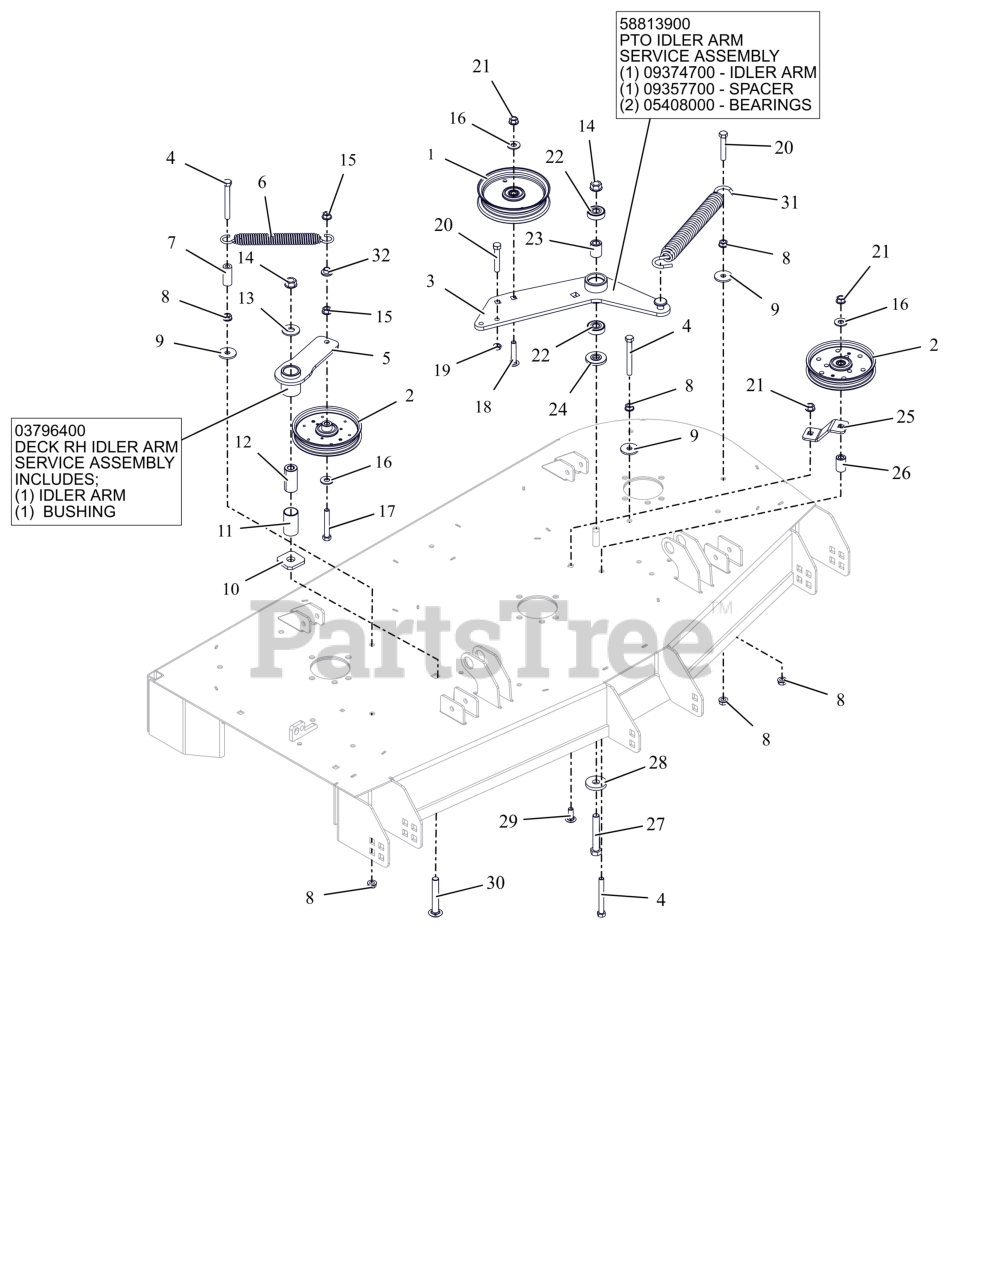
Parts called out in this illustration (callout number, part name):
1	IDLER- FLAT - 5.00" X .75"
2	IDLER- 5" FLANGED
3	WLDMT, IDLER ARM PT660
4	BLT, HEX .38-16X3.25 G5 ZCC
5	WMT, IDLER ARM - BLACK
6	SPRING- EXTENSION
7	HOSE, .38 X 1.65
8	NUT, SPNLK-FLG .38-16 G5 ZCC
9	WSHR,FLT .406X1.375X.135 ZCC
10	WSHR-FLT .640X1.75X.250
11	BSHG, 1.00X1.125X1.937
12	BSHG, SPCR .502X.997X2.03 PM
13	WSHR,FLT .563X1.375X.109 ZCC
14	NUT-LK-CTR-FLG .500-13 GG ZCC
15	NUT-LK-CTR-FLG .375-16 GF ZCC
16	WSHR,FLT .438X1.00X.083 ZCC
17	BLT, HEX .38-16X2.50 G5 ZCC
18	BLT,RHSSN.375-16X2.00 G5 ZCC
19	NUT-JAM .375-16 G2 ZCC
20	BLT,HEX .38-16X2.25 G5 ZCC
21	NUT-LK-CTR-FLG .375-16 GF ZCC
22	BRG-BALL .500X1.38X.437
23	SPACER .510 X .867 X 1.1485
24	SPACER, IDLER ARM
25	PTO FIXED IDLER MTG BRKT-ORG
26	BUSHING, SLV .380X.750X1.190
27	BLT,HEX .50-13X3.25 G5 ZCC
28	WSHR-FL-STL 0.557X1.625X0.25 ZCC
29	BLT,RHSSN .38-16X1.00 G5 ZCC
30	BTL,RHSSN .500-13 X 3.25 G5 ZCC
31	SPRING, EXTENSION
32	BSHG-FLG .385X.500X.875X.406
